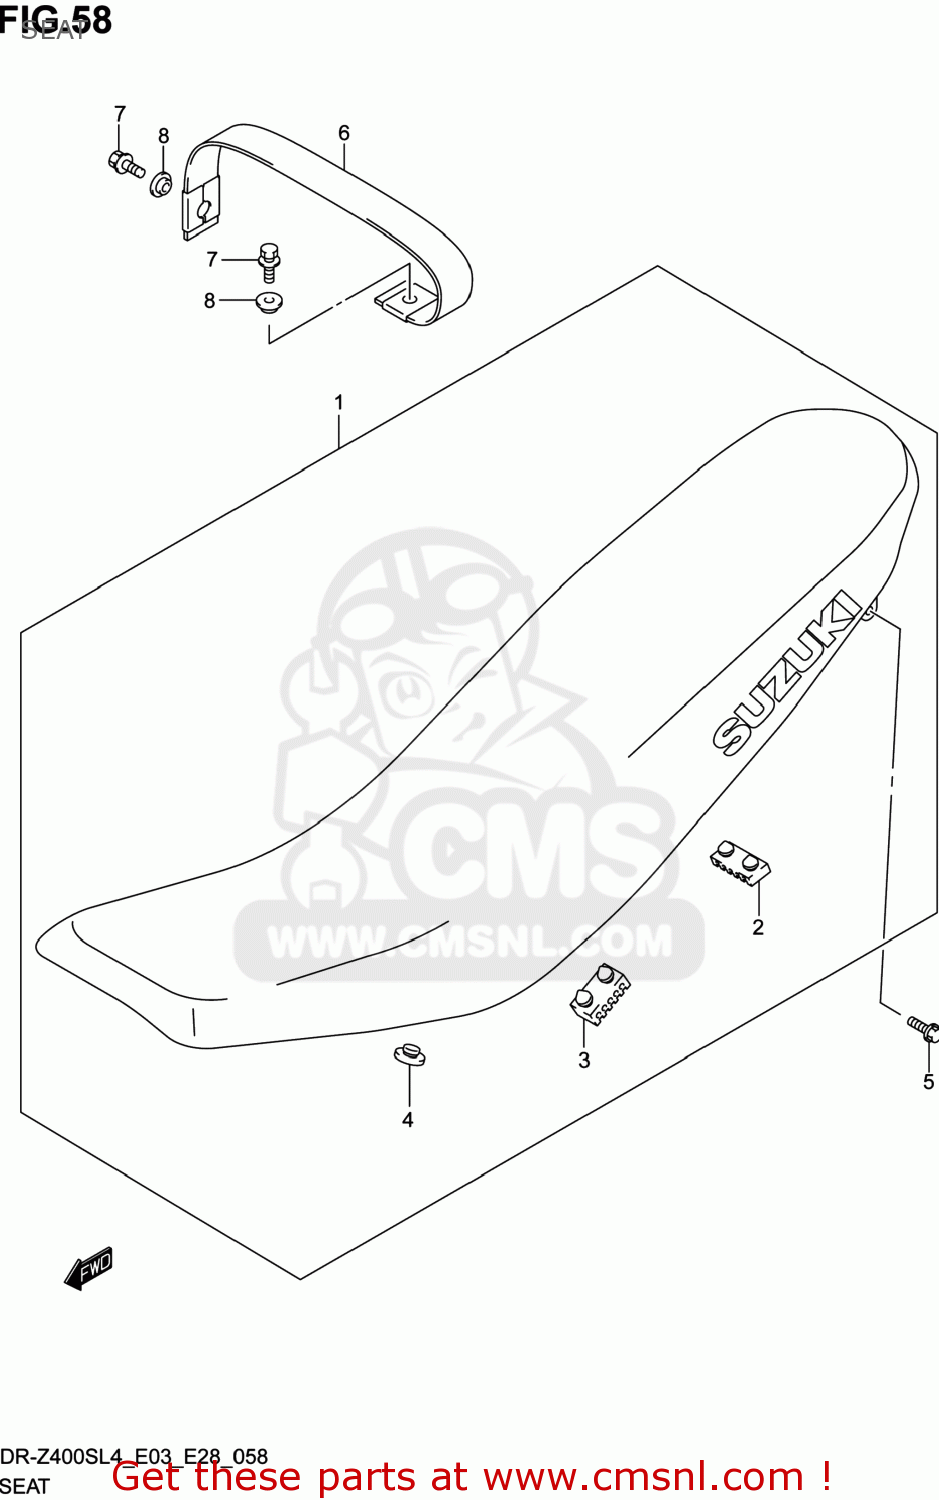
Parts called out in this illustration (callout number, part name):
1	SEAT ASSY,HIGH,SILVER
2	CUSHION,SEAT(40X20X6)
3	CUSHION,SEAT(40X20X15)
4	CUSHION
5	BOLT(6X20)
6	BAND ASSY,SEAT(GRAY)
7	BOLT(6X25)
8	WASHER
